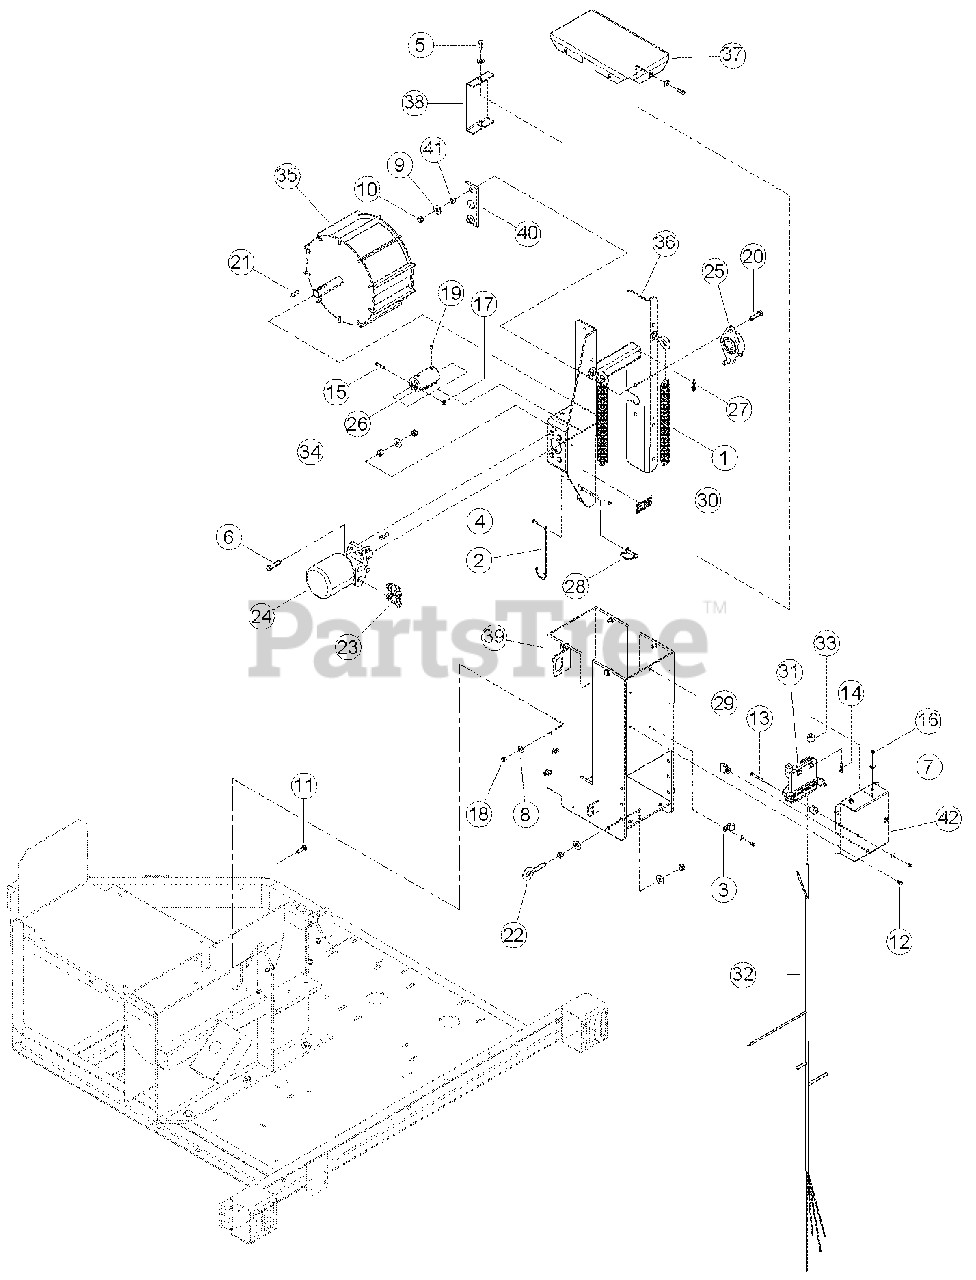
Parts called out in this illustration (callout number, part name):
1	SPRING, EXTENSION
2	LANYARD, NYLON
3	CLAMP, 9/16 COATED
4	BOLT, 1/4 X 3/4 HEX HD GR5 ZP
5	BOLT, 3/8 X 1 HEX HD GR5 ZP
6	BOLT, 1/2 X 2 HEX HD GR5 ZP
7	WASHER, 1/4 FLAT ZP
8	WASHER, 3/8 FLAT ZP
9	WASHER, 1/2 FLAT ZP
10	NUT, 1/2 CENTERLOCK GRB ZP
11	BOLT, 3/8 X 1-1/2 CRG GR5 NC ZP
12	BOLT, 1/4 X 1/2 HCS GR5 ZP
13	BOLT, 1/4 X 2-1/4 HCS GR5 ZP
14	BOLT, 1/4 X 1-1/4 HCS GR5 ZP
15	BOLT 5/16 X 1-1/2 HEX HD GR5 ZP
16	NUT, 1/4 NE NYLOCK ZP
17	NUT, 5/16 NE NYLOCK ZP
18	NUT, 3/8 NE NYLOCK ZP
19	SET SCREW, 3/8 X 1/2 CUP PT SKT
20	BOLT, 1/2 X 1-3/4 HCPS GR5 NC ZP
21	KEY, 5/16 X 1-1/2 SQUARE
22	I-BOLT, 1/2 X 2 ZP
23	ADAPTER, -10 MORING / -8 MJIC 45 DEG.
24	MOTOR, 45 CU. IN. HYDRAULIC
25	BEARING, 1-1/4 DIA. 2 BOLT FLANGE
26	COUPLER, 1-1/4 SHAFT
27	WEAR PAD, STD. SPRING HD FRONT
28	PIN, SHAP 3/8 X 1-1/2 USEABLE LENGTH
29	CIRCUIT BREAKER, 10 AMP RESETTABLE
30	DECAL, CRUSHING ISO
31	CONTROLLER, PLUS 1 CHIPPER
32	HARNESS, 9 IN. TRAILER - PLUS 1
33	BUMPER, 1 OD. W/1-1/4 STUD
34	SPACER, .75 X .62
36	WELDMENT, ROLLER SLIDE
37	WELDMENT, TOP ROLLER COVER
38	SHIELD, COUPLER
39	WELDMENT, ROLLER SUPPORT
40	BEARING, SLIDE
41	SPACER, .75 OD. X .5 ID. X .37
42	ENCLOSURE, PLUS 1 MOUNT
